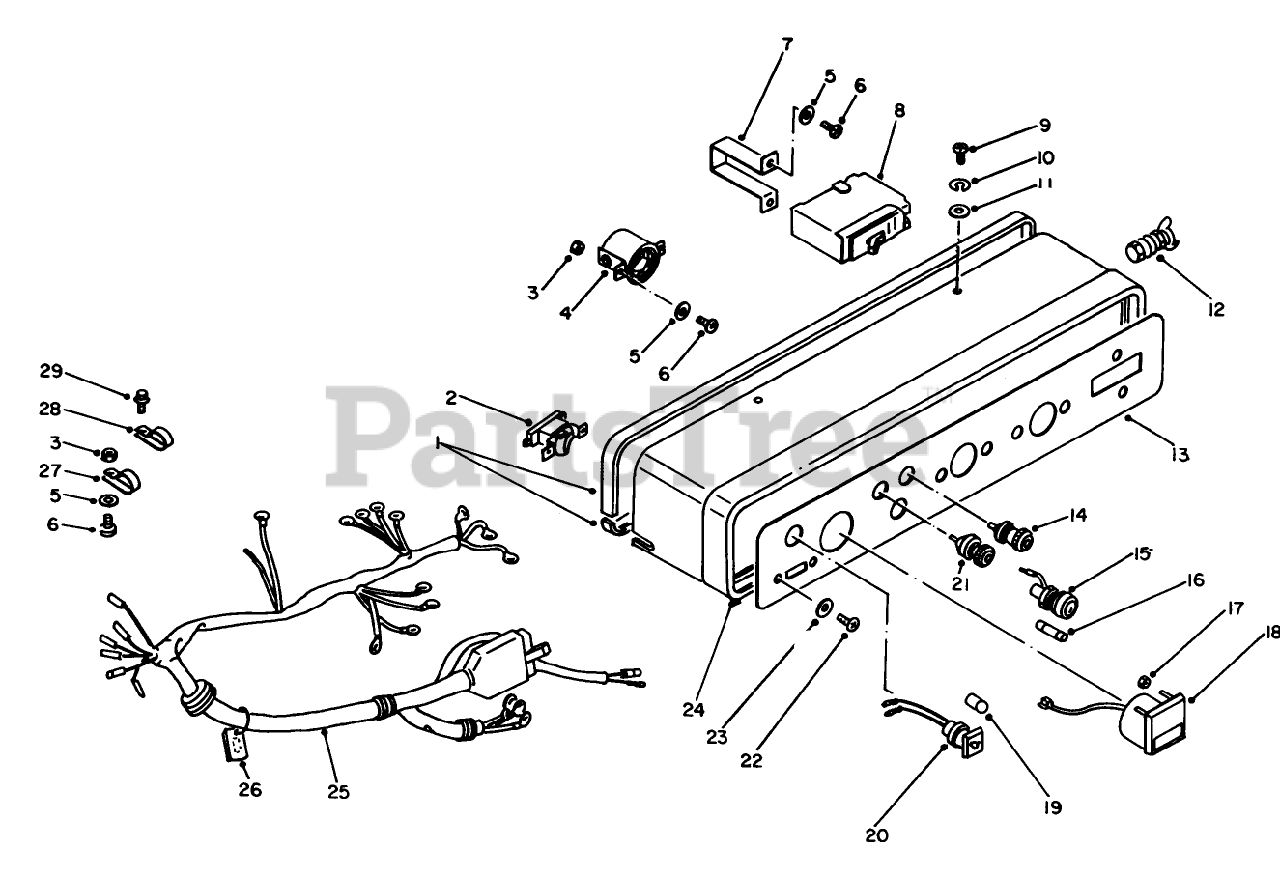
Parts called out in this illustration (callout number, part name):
2	Switch
4	Receptacle
5	Washer
6	Screw
7	BREAKER HOLDER
8	CIRCUIT BREAKER
9	SCREW
10	Washer
11	WASHER
12	Terminal
13	Plate-Panel
14	Terminal
15	Fuse Holder (Incl. Ref. #16)
18	Meter-Voltage
20	Lamp (Incl. Ref. #19)
21	TERMINAL (-)
22	SCREW
23	Washer
24	Control panel
25	Wire Harness
26	Fuse-Spare
27	Clamp
28	Clamp
29	SCREW-HHF
